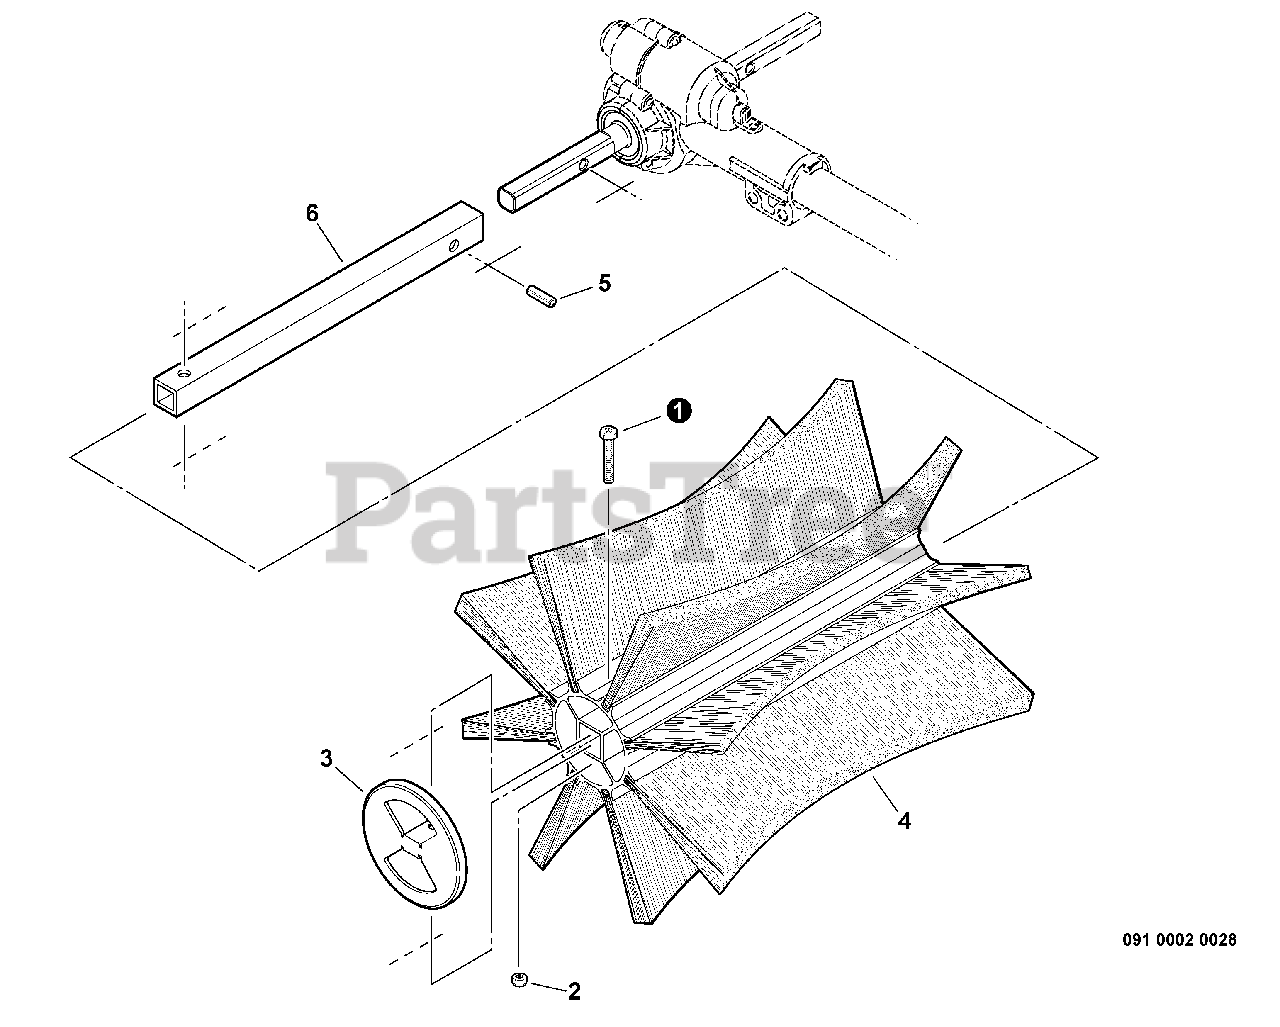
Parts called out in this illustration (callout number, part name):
1	SCREW - 5X30
2	LOCKNUT - 5
3	CAP, END
4	BRUSH ASSY - .028 INCH
5	PIN - SPRING
6	COUPLING, SHAFT
